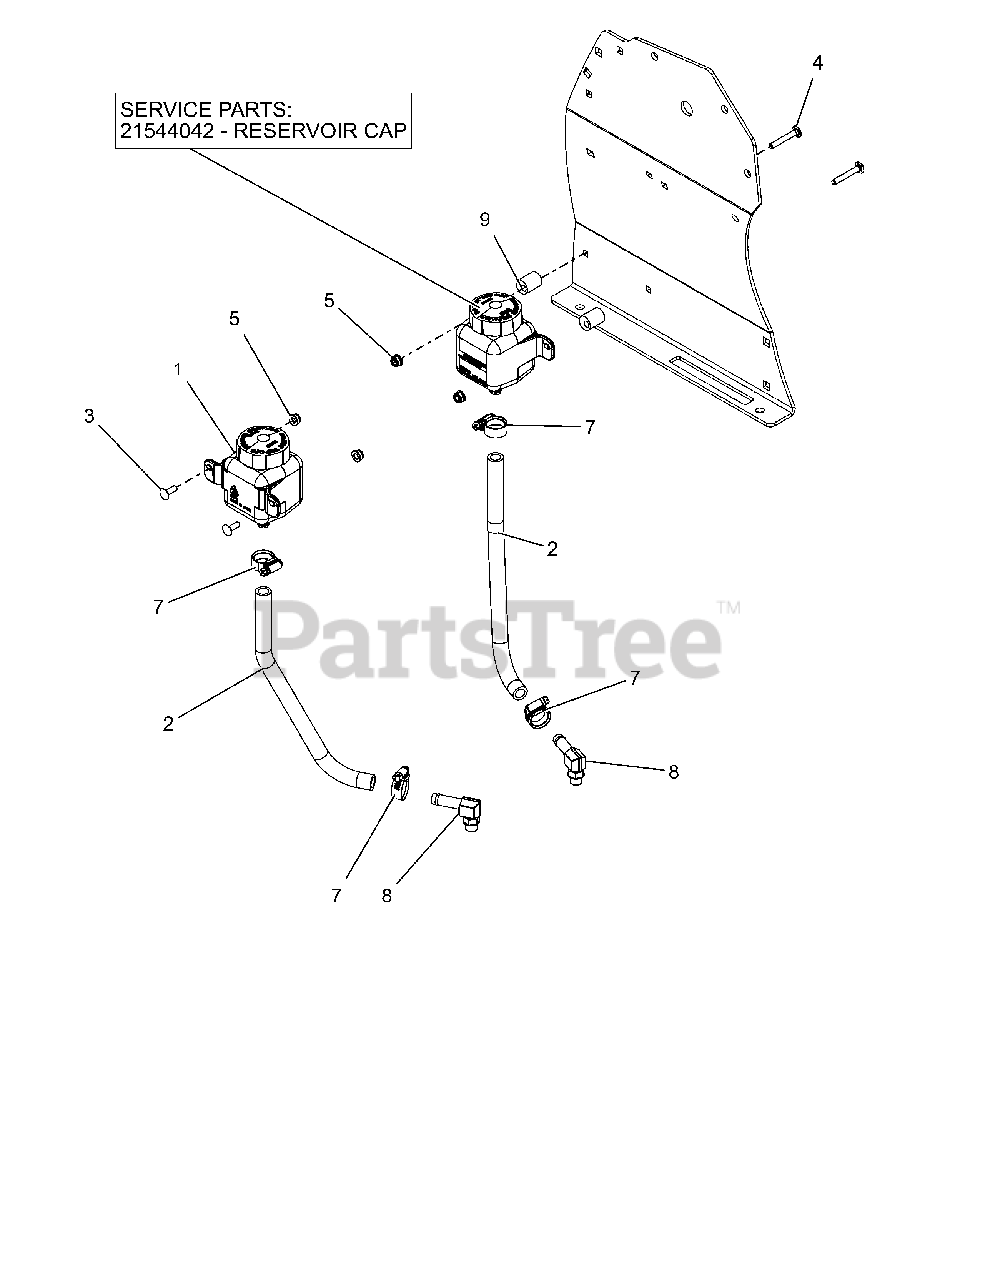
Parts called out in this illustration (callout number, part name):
1	TANK, EXPANSION
1	CAP, HYDRO RESERVOIR REPLAC.
2	HOSE, PROSTANCE HYDRO OVERFLOW
3	@BLT-RDHDSQNK .25-20X.75 G5YZ
4	BLT-RDHDSQNK .25-20X1.75 G5YZ
5	@NUT-LK-NYL-FLG .25-20 YWZC
7	CLAMP,.88 DIA. HOSE
8	FITTING, HYD (90 DEG)
9	ECCENTRIC
